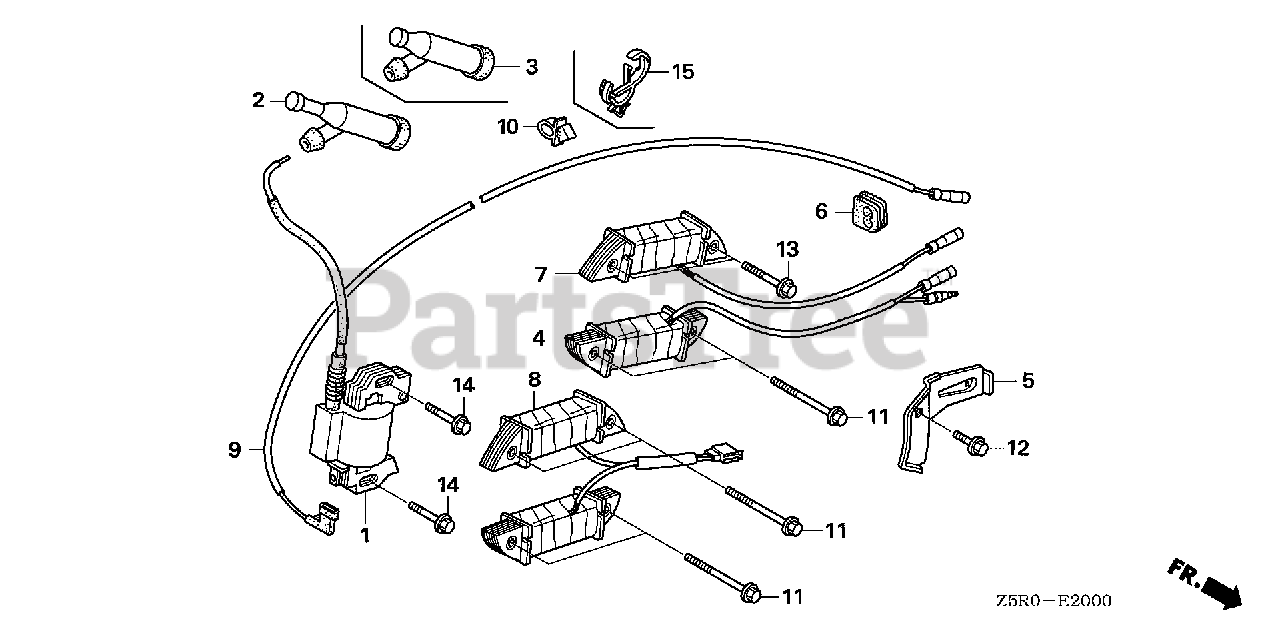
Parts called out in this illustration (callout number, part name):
1	COIL ASSY., IGNITION
2	CAP ASSY., NOISE SUPPRESSOR (NICHIWA Y-EZ RTFM256)
4	COIL ASSY., LAMP (12V/25W)
5	CLAMP, WIRE
6	GROMMET, WIRE
9	WIRE, STOP SWITCH (470MM)
11	BOLT, FLANGE (6X40) (CT200)
12	BOLT, FLANGE (6X12) (CT200)
14	BOLT, FLANGE (6X28) (CT200)
15	CLIP, HARNESS
